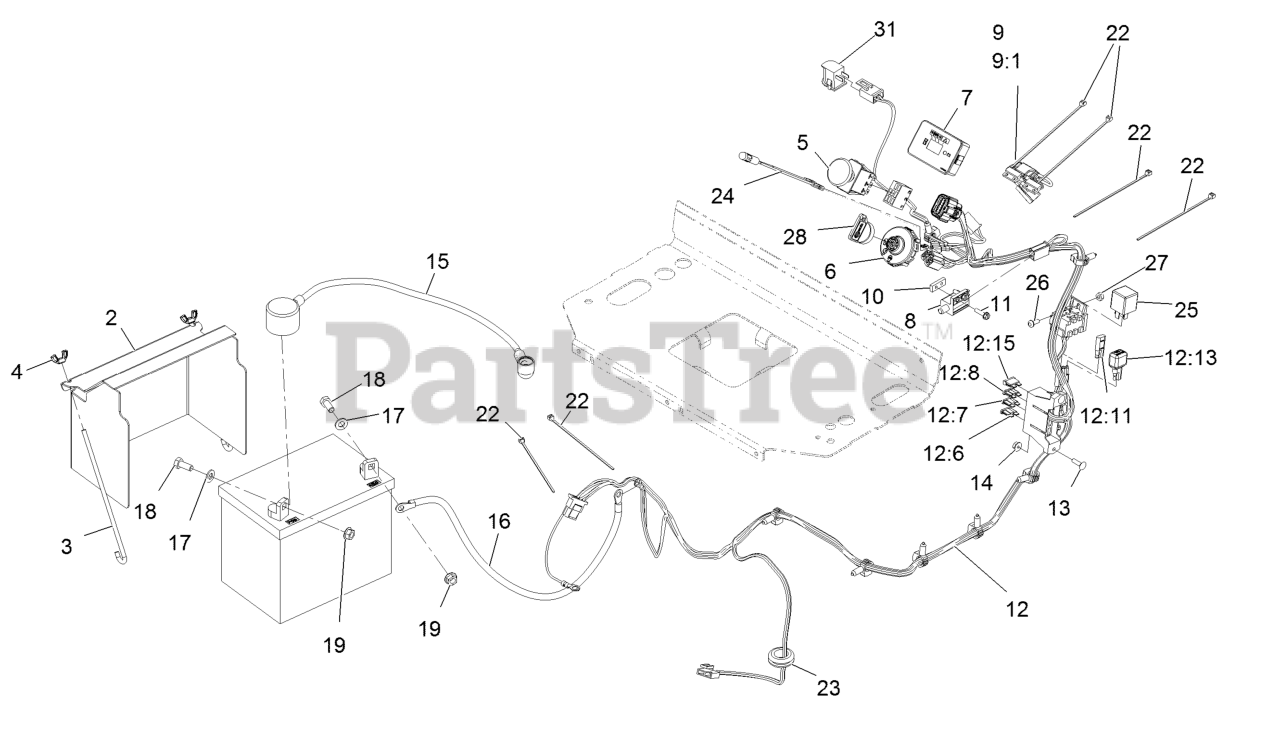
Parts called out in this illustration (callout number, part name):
2	Cover-Battery
3	Bolt-Holddown
4	Wingnut-Nyloc 1/4-20
5	Switch-PTO, On-On-(On)
6	Switch-Ignition
7	Module-Hour Meter
8	Switch-N.C.
9	Harness-Switch, Reed
9:1	Harness-Wire, Reed Switch
10	Plate-Tapped
11	Screw-HWH #10-24 X 3/4
12	Harness, Wire
12:6	Fuse-Blade, 30 Amp
12:7	Fuse-Blade, 25 Amp
12:8	Fuse-Blade, 10 Amp
12:11	Cap-Plug
12:15	Fuse-Blade, 15 Amp
13	Screw-CARR
14	Nut-Whizlock #10-24
15	Cable-Battery, Positive
16	Cable-Battery, Black
17	Washer-5/16 SAE
18	Screw-HH 5/16-18 X 3/4
19	Nut-Hex Flange 5/16-18
22	Tie-Cable 5 1/2 (Small)
23	Grommet
24	Indicator-Red LED
25	Relay-12Vdc 40 Amp
26	Screw-PPH #10-24 X 1/2
27	Nut-Nyloc #10-24
28	Key-Exmark Logo
